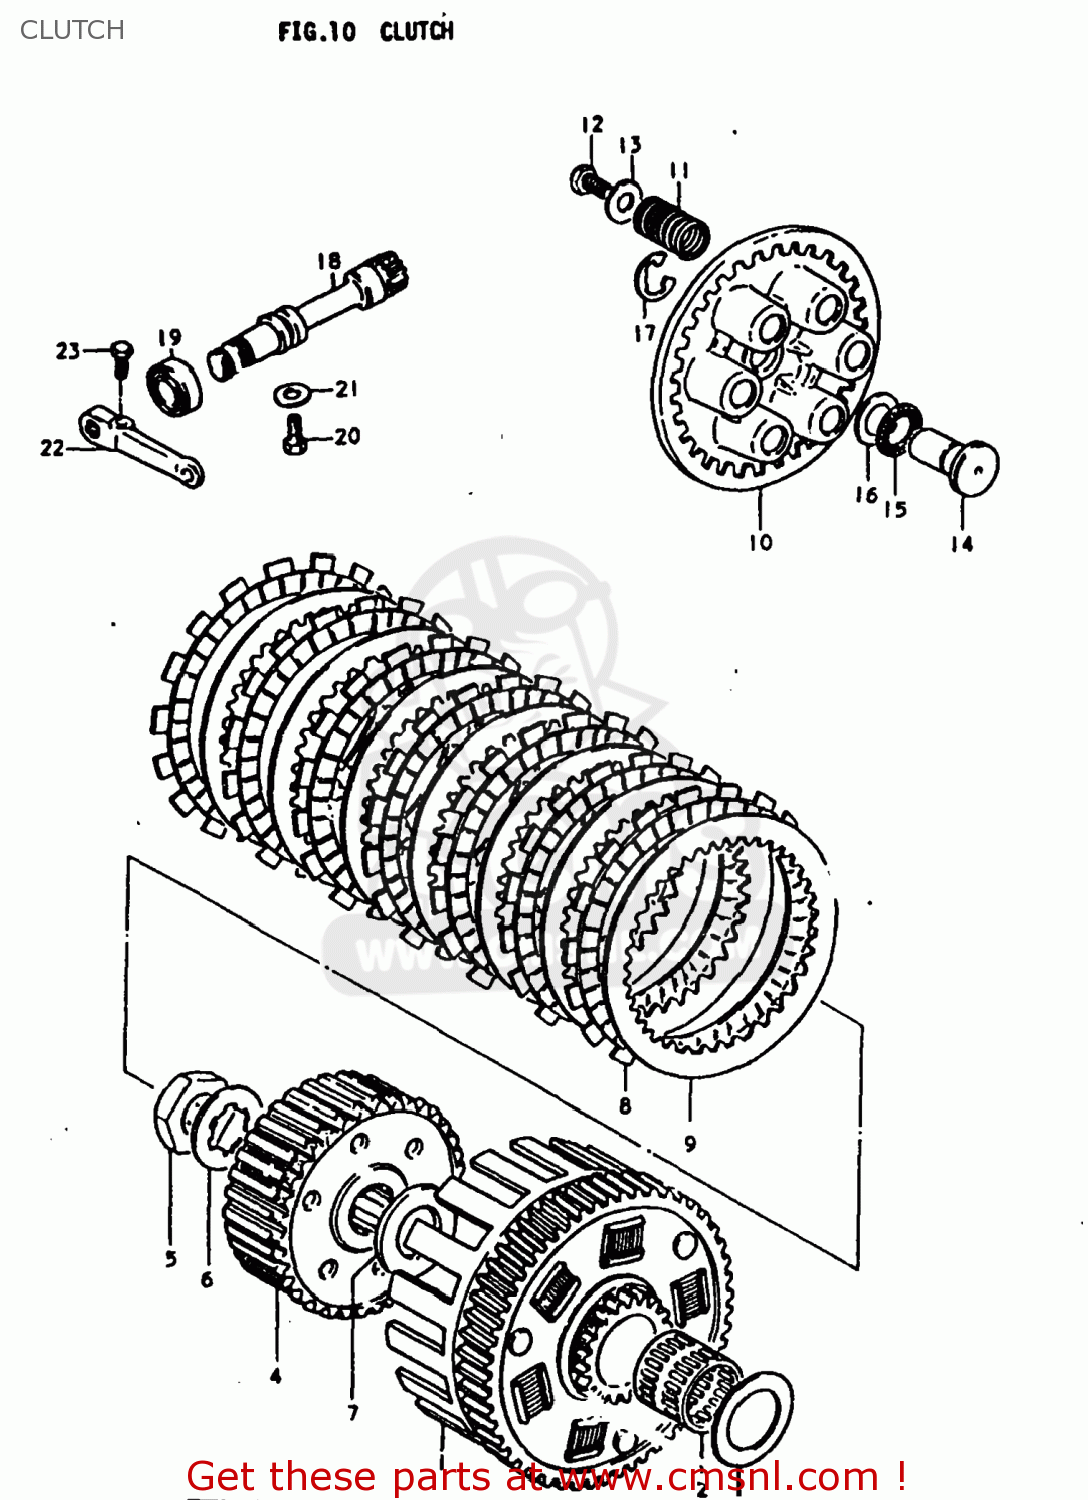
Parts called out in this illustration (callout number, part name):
1	GEAR ASSEMBLY,PRIMARY DRIVE
2	ROLLER BEARING (25X30X3
3	WASHER(25X41X3)
4	HUB,CLUTCH SLEEVE
5	NUT (20MM)
6	WASHER,LOCK
7	WASHER(20X44X3)
8	PLATE,CLUTCH DRIVE (MCA)
9	PLATE,CLUTCH DRIVEN(T:2.0) (NAS)
10	DISC,CLUTCH PRESSURE
11	SPRING
12	BOLT, UPPER
13	WASHER
14	RACK,CLUTCH RELEASE
15	BEARING(15X28X2)
16	WASHER
17	E RING 12MM
18	PINION,CLUTCH RELEASE
19	OIL SEAL
20	BOLT(6X12)
21	WASHER
22	ARM,CLUTCH RELEASE
23	BOLT
